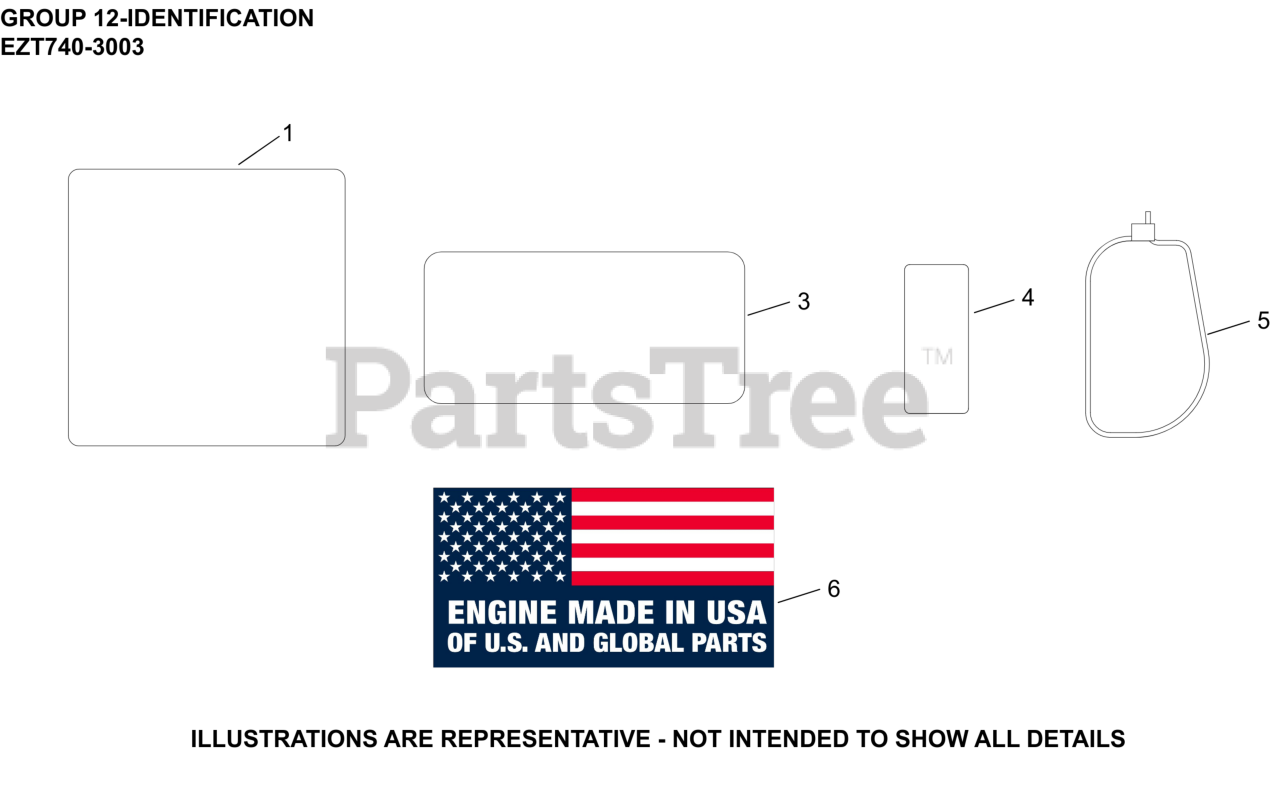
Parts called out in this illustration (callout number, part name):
1	LABEL, CONFIDANT (EZT740, 25HP)
3	LABEL, CANADIAN COMPLIANCE
4	LABEL, CLEAR LAMINATION
6	DECAL, USA
